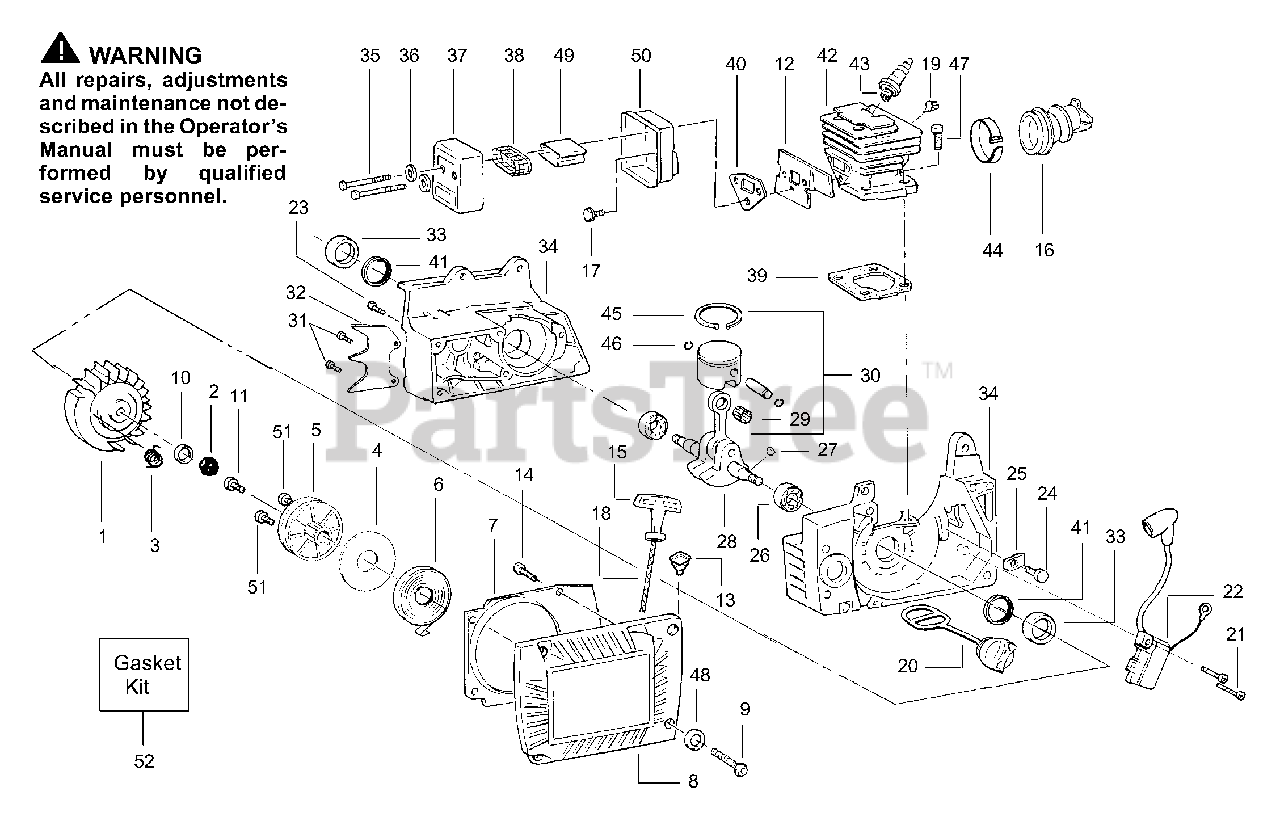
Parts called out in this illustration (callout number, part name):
1	Flywheel Ass'y.
2	Nut-Flywheel
3	Spring-Starter Dog
5	Starter Pulley
6	Starter Spring
7	Baffle Plate
8	Fan Housing
10	Washer-Conical
12	Muffler Back Plate Model 3450 T1 & T2
12	Muffler Back Plate Model 3750 T1
12	Muffler Back Plate Model 3750 T2 & 3450 T3 & T4
13	Eyelet Replacement Kit
15	Starter Handle
18	Rope Kit
20	Oil Cap Ass'y.
21	Screw
22	Ignition Module
26	Crankshaft Bearing
27	Flywheel Key
28	Connecting Rod Ass'y.
29	Piston Pin Bearing
30	Piston Kit Model 3450 T1,T2,T4
30	Piston Kit Model 3750 T1 & T2, 3450 T3
33	Crankshaft Seal
34	Crankcase Ass'y. Model 3450 T1
34	Crankcase Ass'y. Model 3450 T2,T3,T4 3750 T1 & T2
35	Screw Model 3450 T1 & T2
35	Screw Model 3750 T1 & T2, 3450 T3,T4
37	Muffler Cover Ass'y. Model 3450 T1 & T2
37	Muffler Cover Ass'y. Model 3750 T1
37	Muffler Cover Ass'y. Model 3750 T2 & 3450 T3,T4
38	Spark Arrestor Screen
39	Cylinder Gasket KIT Model 3450 T1
39	Cylinder Gasket KIT Model 3450 T2,T4
39	Cylinder Gasket KIT Model 3750 T1 & T2 3450 T3
40	Muffler Gasket Model 3450 T1
40	Muffler Gasket Model 3450 T2,T4
40	Muffler Gasket Model 3750 T1 & T2 3450 T3
41	Snap Ring
42	Cylinder Ass'y. Model 3450 T1
42	Cylinder Ass'y. Model 3450 T2,T4
42	Cylinder Ass'y. Model 3750 T1 & T2 3450 T3
43	Spark Plug RCJ-4
43	Spark Plug RCJ-6Y
44	Clamp Ass'y.
45	Piston Ring Model 3450 T1,T2,T4
45	Piston Ring Model 3750 T1 & T2 3450 T3
46	Retainer
49	Muffler Diffuser Model 3450 T1 & T2
49	Muffler Diffuser Model 3750 T1 & T2 3450 T3,T4
50	Muffler Body Model 3450 T1 & T2
50	Muffler Body Model 3750 T1
50	Muffler Body Model 3750 T2 & 3450 T3,T4
51	Screw-Starter Pulley
52	Kit-Gasket
